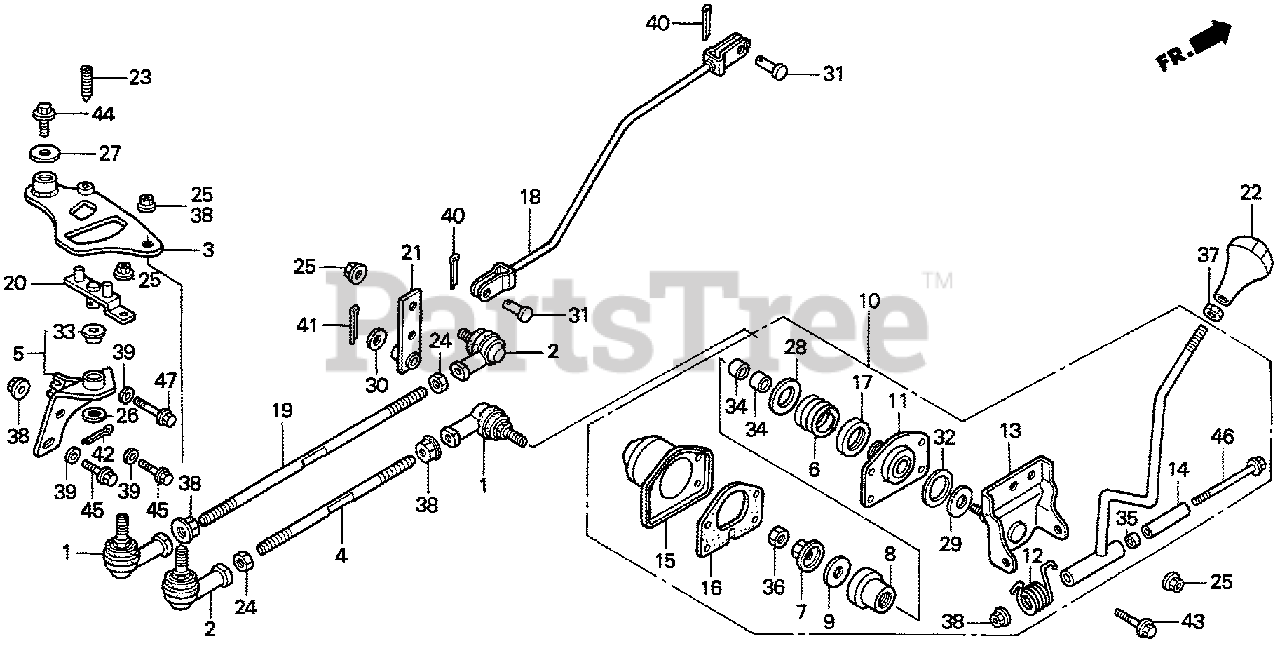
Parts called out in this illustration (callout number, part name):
1	JOINT, R. BALL
2	JOINT, L. BALL
3	ARM, CONTROL
4	ROD, GEARSHIFT
5	BRACKET ASSY., RETURN ARM
6	SPRING, FRICTION
7	WASHER SET, FRICTION
7	WASHER, FRICTION SETTING
8	COLLAR, FRICTION SPRING
9	WASHER, FRICTION (15X40X3)
10	LEVER ASSY., CHANGE
11	HOLDER, CHANGE LEVER
12	SPRING, CHANGE LEVER
13	SHAFT, CHANGE LEVER
14	COLLAR, CHANGE LEVER JOINT
15	COVER, FRICTION
16	GASKET, FRICTION COVER (NOT AVAILABLE)
16	GASKET, FRICTION COVER
17	GUIDE, SPRING
18	ROD, RETURN (A)
19	ROD, RETURN (305MM) (C)
20	ARM A, RETURN
21	ARM B, RETURN
22	KNOB, SHIFT LEVER
23	SCREW, FIXING (8X1.25)
24	NUT, HEX. (8MM)
25	NUT, FLANGE (M8X1.25) (SELF-LOCK)
25	NUT, FLANGE (8MM)
26	WASHER (16X22)
27	WASHER (8MM) (NOT AVAILABLE)
28	WASHER (31X46X1)
29	WASHER (15.5X40X2) (NOT AVAILABLE)
29	WASHER (15.5X36X2)
30	WASHER (13X20)
31	PIN (10X18)
32	DUST SEAL
33	BUSH (16X18X25)
34	BUSH (15X17X12)
35	COLLAR (13X19.1X10)
36	NUT, HEX. (10MM)
37	NUT, HEX. (12MM)
38	NUT, FLANGE (8MM)
39	WASHER, PLAIN (8MM)
40	PIN, SPLIT (2.5X30)
41	PIN, SPLIT (2.5X30)
42	PIN, SPLIT (3.0X25)
42	PIN, SPLIT (3.0X45)
43	BOLT, FLANGE (6X14)
44	BOLT, FLANGE (8X20)
45	BOLT, FLANGE (8X45)
46	BOLT, FLANGE (8X80)
47	BOLT, FLANGE (8X115)
